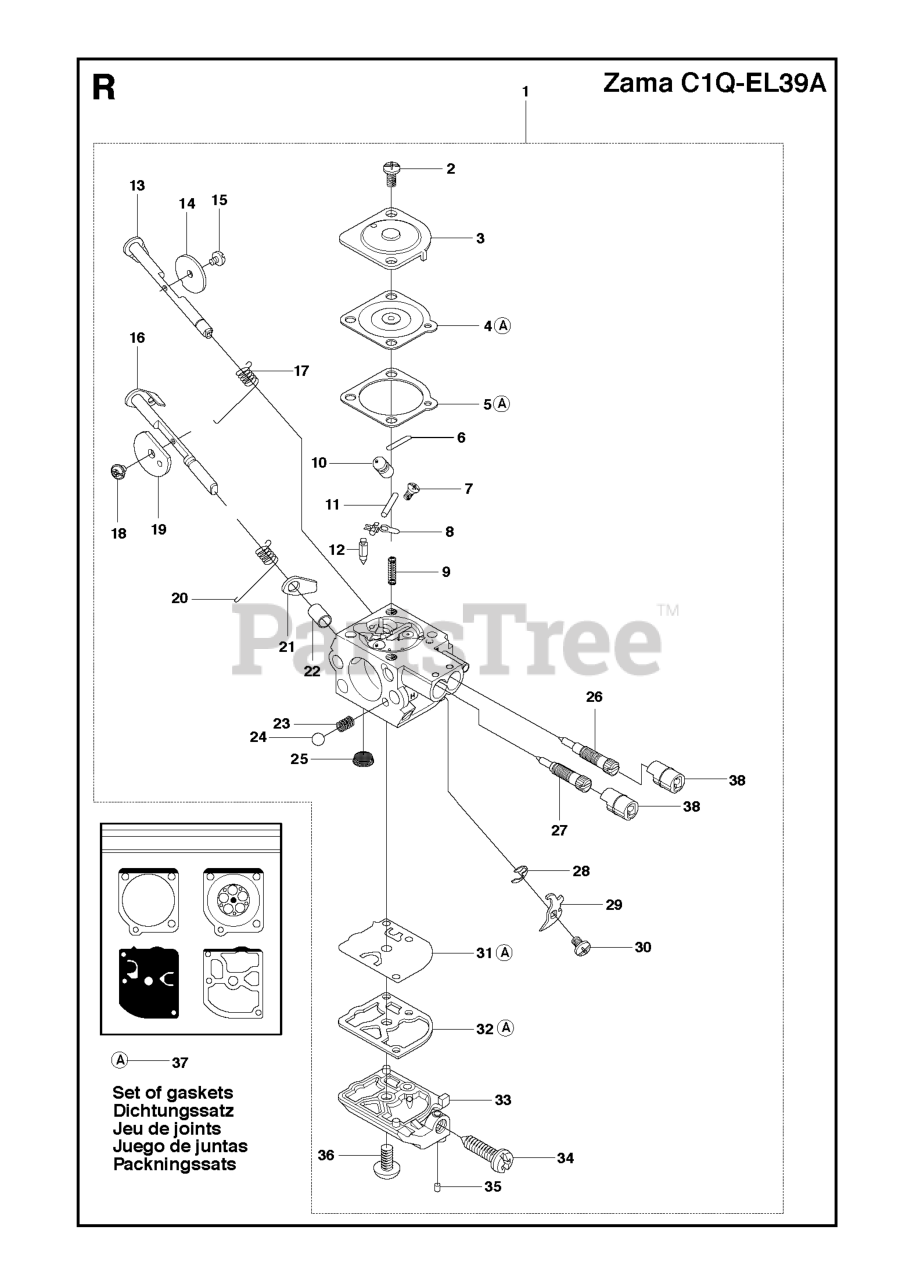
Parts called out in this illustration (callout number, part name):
1	CARBURETTOR C1Q-EL39A
9	SPRING
11	PIN RETAINING SCREW
12	INLET NEEDLE
13	SHAFT ASSY
16	SHAFT ASSY
17	RETURN SPRING
25	FUEL INLET SCREEN
26	SCREW IDLE MIXTURE
27	SCREW MAIN MIXTURE
28	CLIP
31	PUMP DIAPHRAGM
37	GASKET KIT (ZAMA GND39)
38	LIMITER CAP KIT
